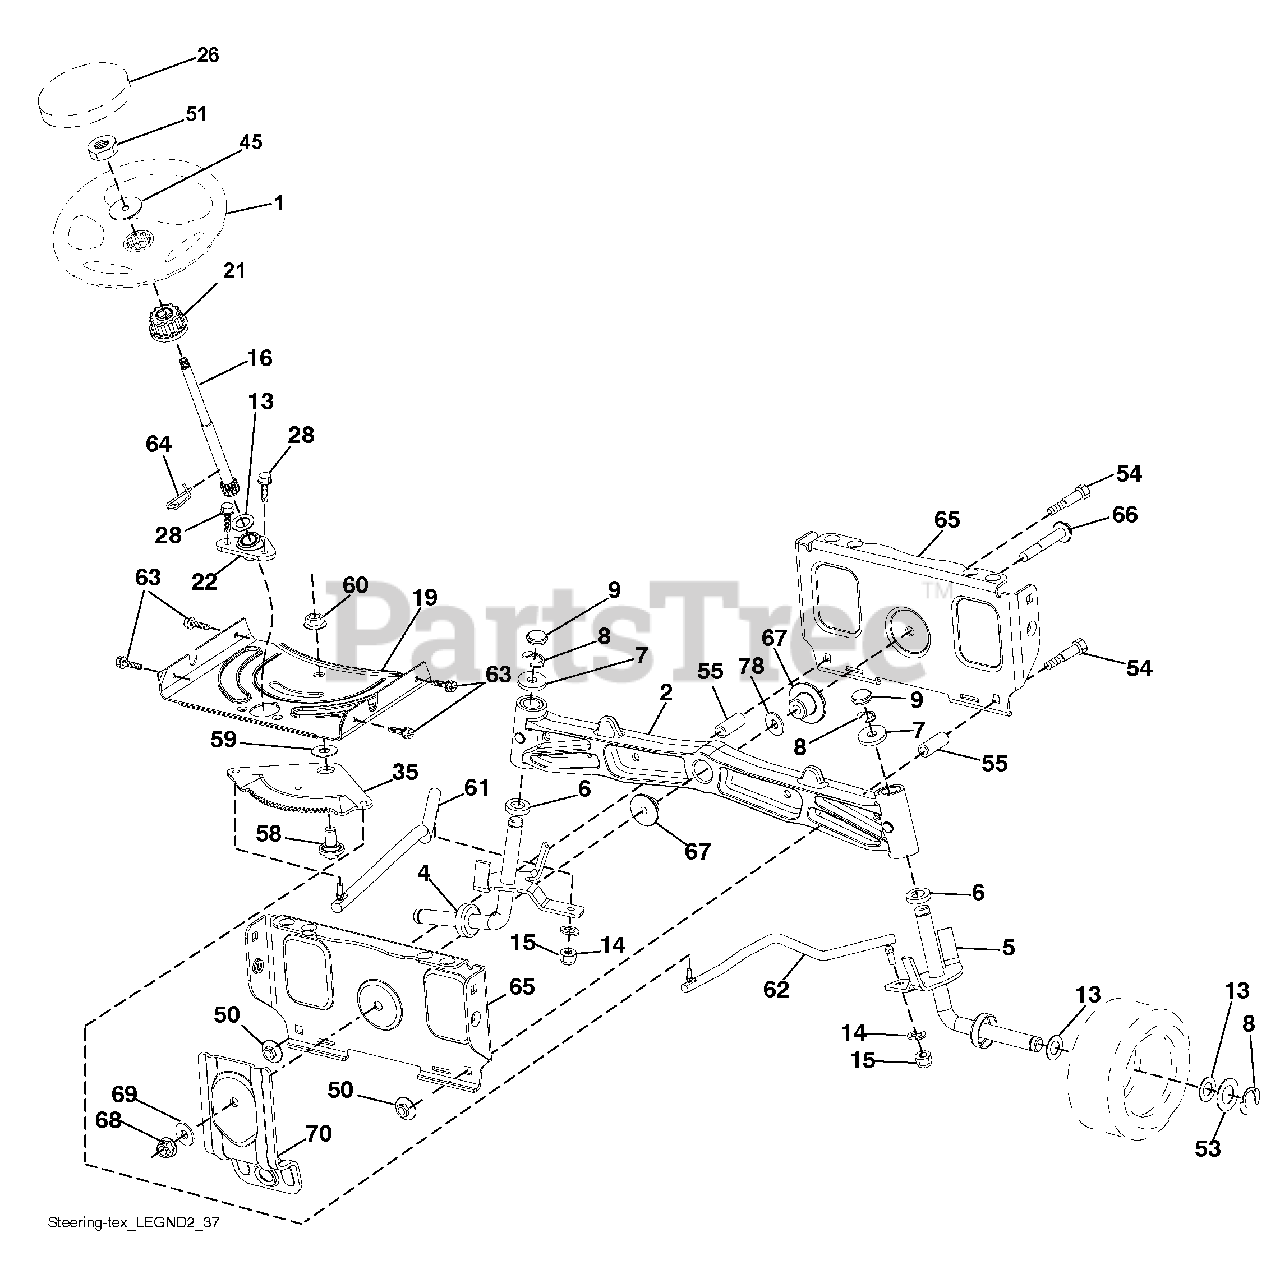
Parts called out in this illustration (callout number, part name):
1	Wheel, Steering
2	Axle Asm., Front
4	Spindle Asm., LH
5	Spindle Asm., RH
6	Bearing, Race Thrust Harden
7	Washer 25/32 x 1-5/8 x 16 Ga.
8	Ring, Clip #T5304-75
9	Cap, Spindle
13	Washer 25/32 x 1-1/4 x 16 Ga.
14	Washer, Lock Hvy Hlcl Spr 3/8
15	Nut, Crown Lock 3/8-24 unf
16	Shaft Steering
19	Plate Steering
21	Adapter, Wheel Steering
22	Supt. Strg. Lower
26	Insert, Wheel Steering
28	Screw 3/8-16 x 3/4
35	Gear, Sector Plate
45	Washer 9/16 ID x 2-3/8 OD 12 Ga.
50	Nut Lock Flg. 3/8-16 unc
51	Nut Hex Jam Toplock 1/2-20 unf
53	Washer Hardened .793 x 1.637 x .060
54	Bolt Hex HS 3/8-16 unc x 2-1/4
55	Spacer Brace Axle
58	Bolt Shoulder Sector Pivot CFM
59	Washer Thrust Sector Steering
60	Nut Flange Lock 5/8-11
61	Draglink, LH
62	Draglink, RH
63	Screw 5/16-18 x 3/4
64	Retainer Clip Spring Steering
65	Brace Axle Front
66	Bolt Hex Fghd 7/16-14 x 3 Serr
67	Bushing PM Front Axle
68	Nut Lock Flange 7/16-14 Gr. 5
69	Washer 1.5 x .505 x .118
70	Bracket Deck Susp. Front
78	Washer Thrust
